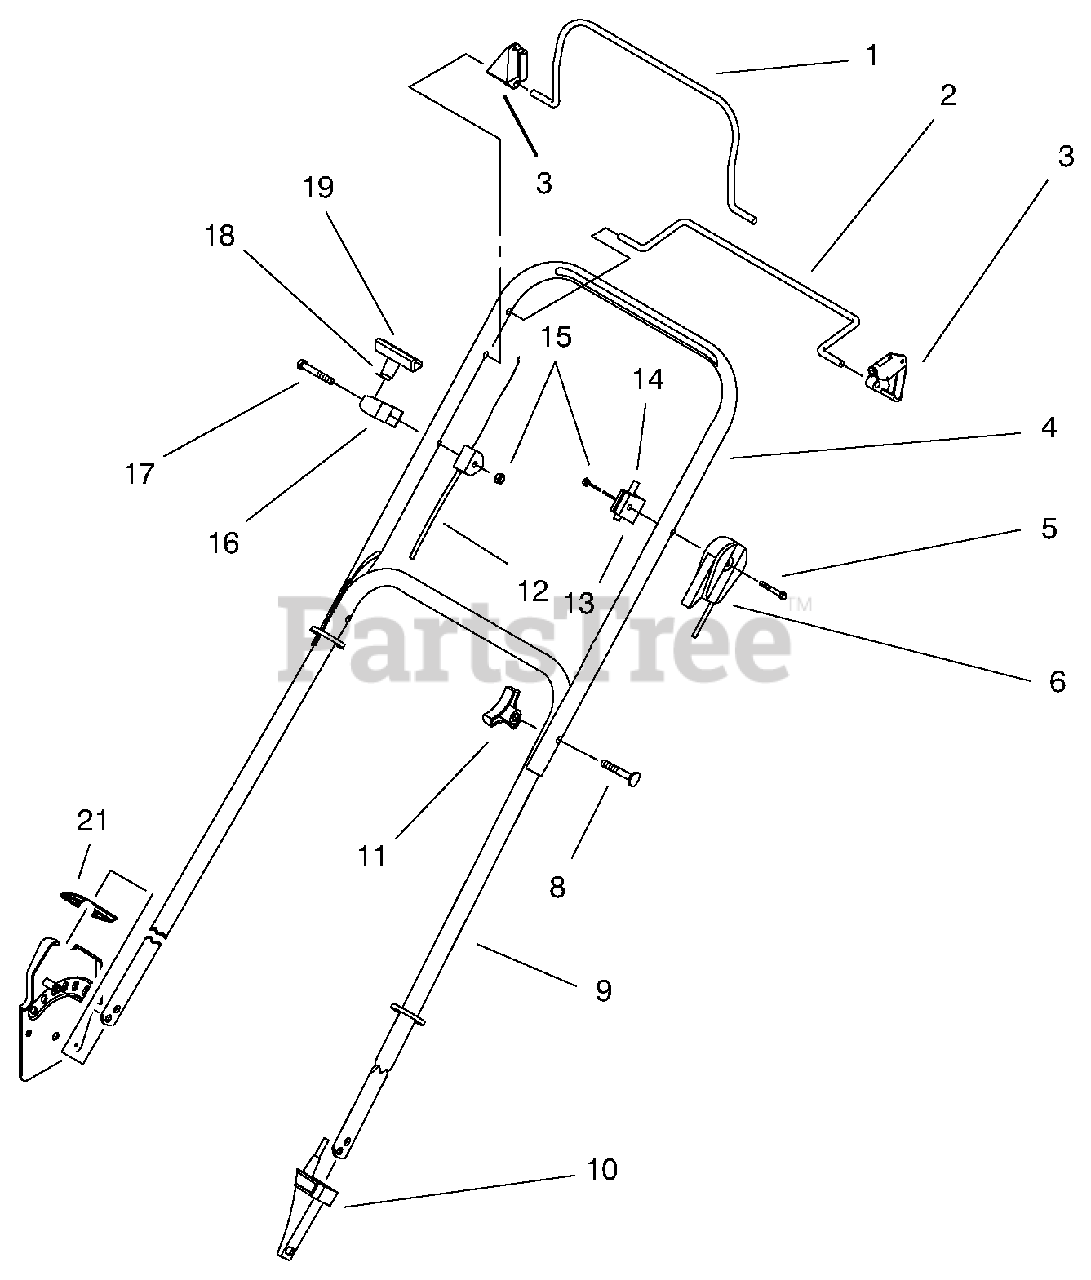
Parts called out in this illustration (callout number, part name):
1	Bail-Flywheel Brake
2	Bail-SP Control
3	Stop-Pivot
4	Handle-Upper
5	Screw-Hex Hd. Cap
6	Cable-Throttle
8	Screw-Handle
9	Handle-Lower
10	Anchor-Cable SP Lower)
11	Knob
12	Cable-Flywheel Brake
13	Anchor-Cable SP Upper
14	Cable-Traction
15	Nut-Lock
16	Guide-Rope
17	Screw-Hex Hd. Cap
18	Handle-Starter
19	Clip-Rope Insert
21	Guard-Handle
